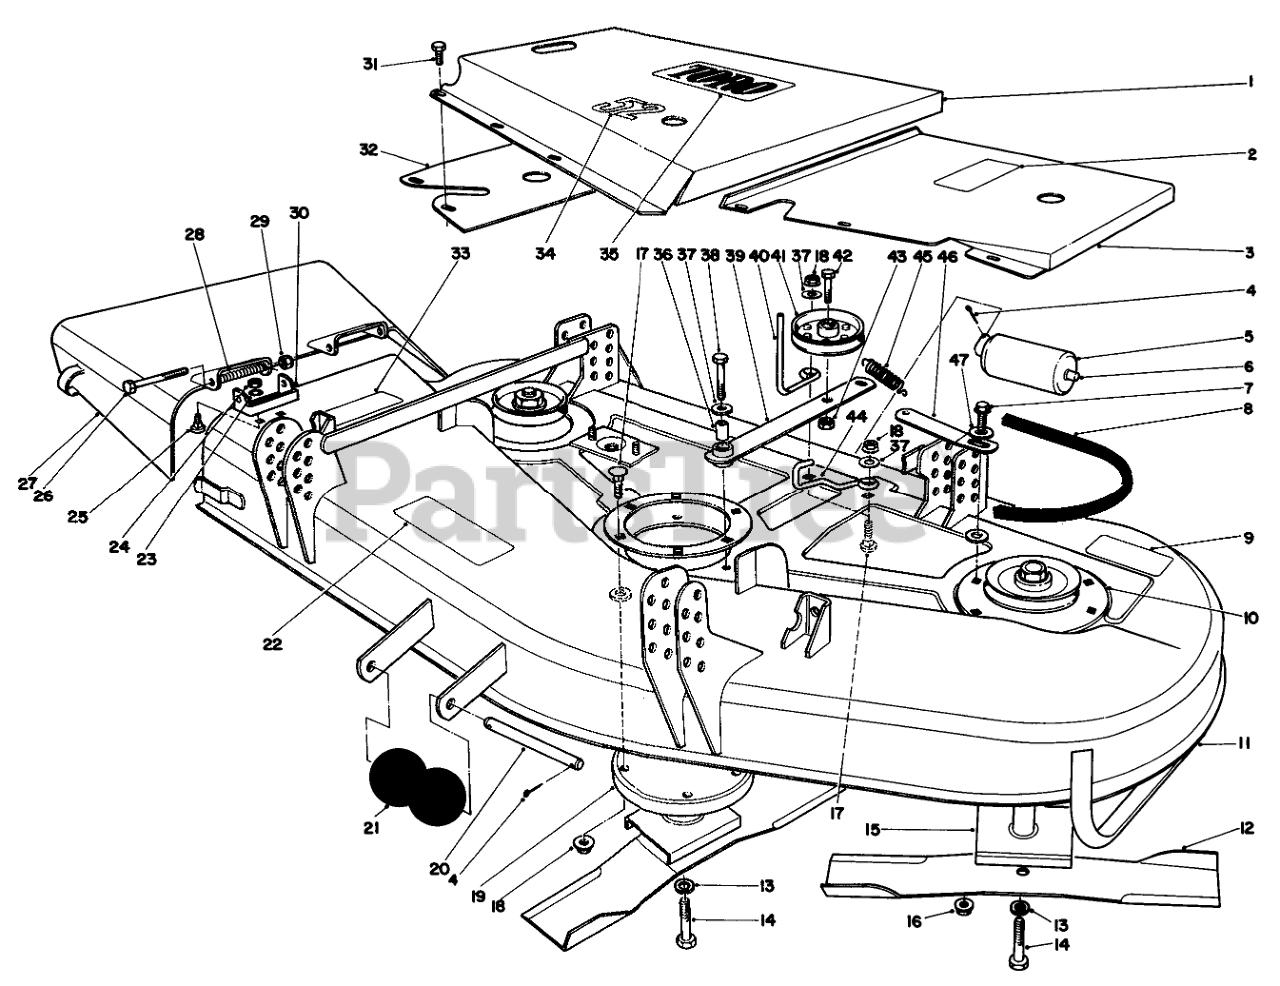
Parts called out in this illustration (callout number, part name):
1	CENTER COVER WA 52 R
2	DECAL
3	Cover
4	PIN-COTTER
5	ROLLER-DECK
6	SHAFT-ROLLER, REAR
7	SCREW-HHF
8	V-BELT
9	DECAL-CAUTION, BLADE
10	SUPPORT-DECK, RING
11	Deck Assembly
12	Blade
13	WASHER-LOCK
14	SCREW-BLADE
15	SPINDLE ASM
16	NUT-LOCK, FLANGE
17	SCREW-CARR
18	NUT-HF
19	HOUSING - SPINDLE ASM
20	SHAFT-ROLLER
21	ROLLER
22	Decal-Caution
23	WASHER-LOCK
24	NUT-HEX
25	SCREW-CARR
26	SCREW-HH
27	Deflector
28	SPRING
29	NUT-HEX
30	Bracket-Pivot
31	SCREW-HHFTF
32	Cover
33	DECAL-CAUTION, DEFLECTOR
34	DECAL
35	Decal-Toro
36	SLEEVE
37	WASHER-FLAT
38	SCREW-HH
39	ARM-IDLER, DECK
40	ROD-BELT
41	Pulley
42	SCREW-HH
43	NUT-HEX
44	BELT GUIDE
45	SPRING-EXTENSION
46	Plate-Spring Support
47	WASHER-FLAT
